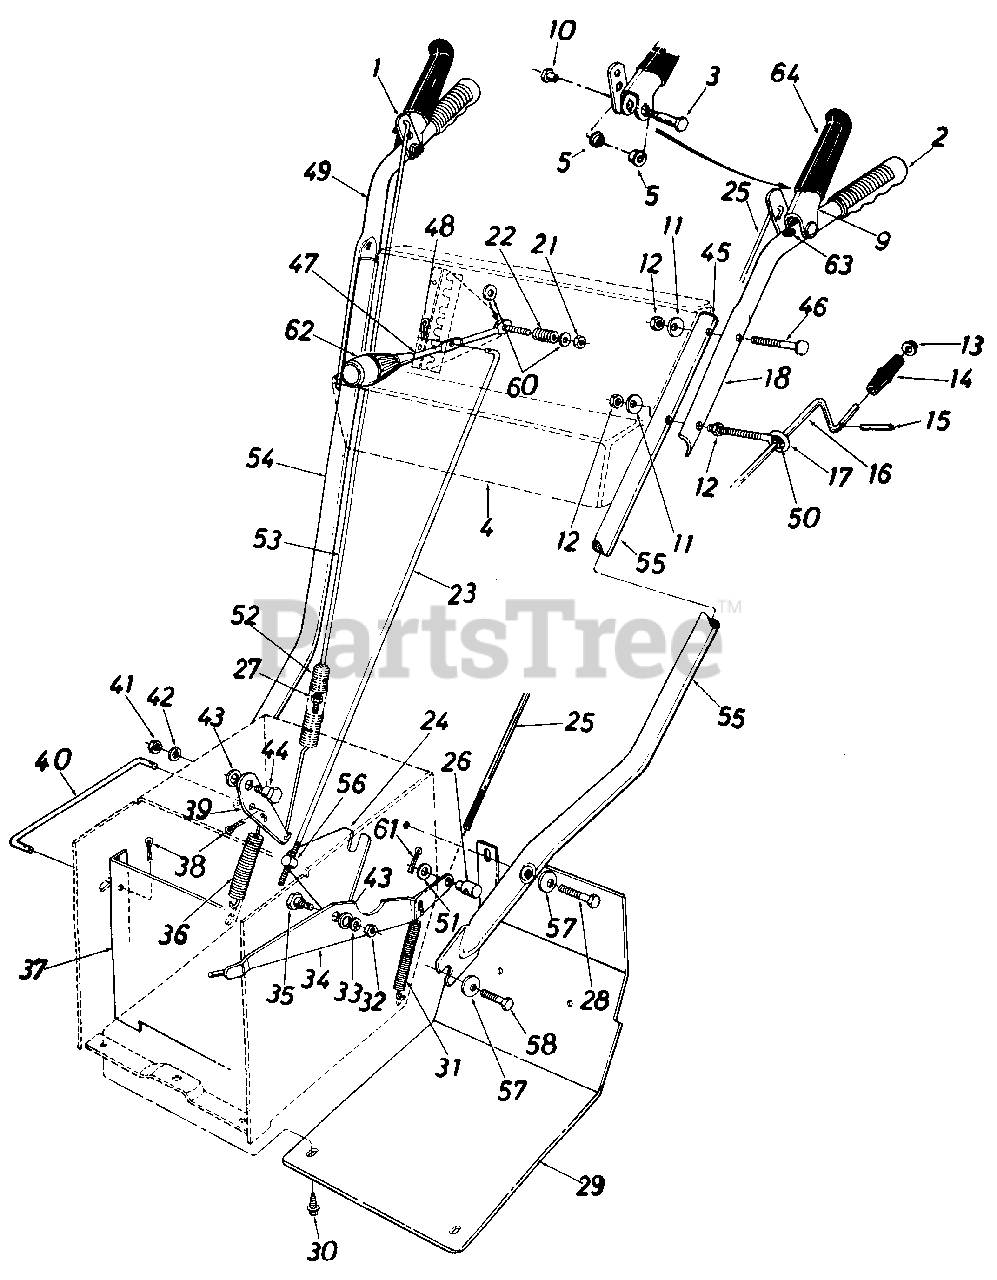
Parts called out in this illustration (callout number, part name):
1	Clutch Grip Ass'y.-R.H.
3	Shoulder Bolt .374 Dia. x 1.375" Lg .
4	Handle Panel Ass'y.
5	Hex Flange Plastic Bearing .380" I.D.
9	Clutch Grip Ass'y.-L.H.
10	Shoulder Nut 1/4-20 Thd.
11	Bell-Wash. .34" I.D. x .88" O.D.
12	Hex Nut 5/16-18 Thd.
13	Push Nut 3/8" Rod
14	Knob 3/8" Rod
15	Roll Pin .12 Dia. X .63" Lg.
16	Chute Crank Ass'y. 39" Lg.
17	Eye Bolt 5/16-18 x 5.0" Lg.
18	Upper Hand e-L.H.
21	Hex Ins. Jam L-Nut 5/16-18 Thd.
22	Compression Spring .50" O.D. x .88" Lg.
23	Shifting Rod 5/16" x 32.50" Lg.
24	Shifting Linkage Bracket
25	Lockout Rod .214" Dia. x 36.0" Lg.
26	Adjustment Ferrule 1/4-20
27	Hex Ins. L-Nut 1/4-20 Thd.
28	Hex Bolt 3/8-16 x 2.00" Lg.
29	Frame Cover
30	Hex Wash. Self-Tap Scr. 1/4-20 x .50" Lg.
31	Extension Spring .38" O.D. x 3.25" Lg.
32	Hex Jam Nut 3/8-16 Thd.
33	L-Wash. 3/8" l.D.
34	Auger Clutch Bracket Ass'y.
35	Shld. Bolt .625" Dia. x .170
36	Extension Spring .75" O.D. X 4.31" Lg.
37	Drive Pulley Support Brkt. Ass'y.
38	Cotter Pin 3/32" Dia. x .75" Lg.'
39	Drive Clutch Bracket
40	Drive Clutch Rod
41	Hex Jam Nut 3/8-16 Thd.
42	L Wash . 3/8" I . D .
43	Bell-Wash. .40" I.D. x 1.13" O.D.
44	Shld. Bolt .625" Dia. x .170
45	Plastic Plug
46	Carriage Bolt 5/16-18 X 2.0" Lg.
47	Shift Handle
48	Int. Cotter Pin 5/16" Dia.
51	Fl-Wash. .344" I.D. x .62" O.D.
52	Extension Spring 75" O.D. x 5 oon Lg.
53	Lockout Rod .214" Dia. x 32" Lg.
54	Lower Handle-R.H.
55	Lower Handle-L.H.
56	Adjustment Ferrule
57	Bell-Wash. 40" l.D. x .88"
58	Hex Wash. Self-Tap Scr. 3/8-16 X 75" Lg.
60	Fl-Wash. 344" l.D. x .62" O.D.
61	Cotter Pin 3/32" Dia.
63	Push Cap
64	Black Vinyl Grip
